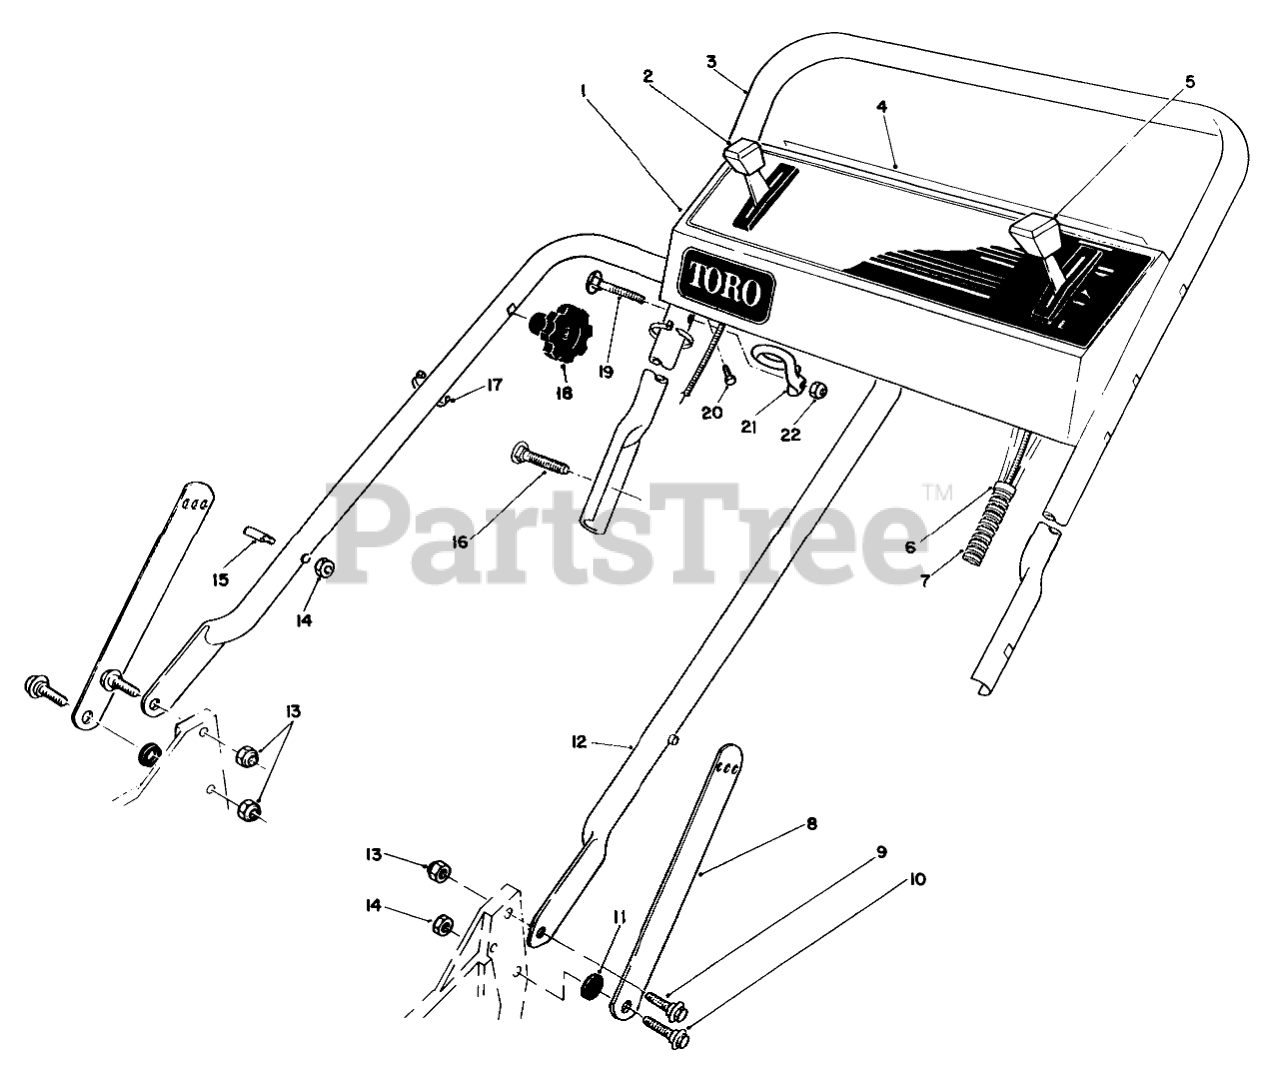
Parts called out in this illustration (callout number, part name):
1	Panel-Control
2	Control-Ground Speed
3	UPPER HANDLE
4	DECAL-PANEL, DANGER
5	THROTTLE CONTROL
6	FITTING-RING
7	CONTROL CABLE COVER
8	Handle Latch
9	SCREW-SHOULDER
10	SCREW-SHOULDER
11	SPACER
12	LOWER HANDLE ASM
13	NUT-LOCK, NI
14	NUT-LOCK, NI
15	HANDLE PIN
16	5/16-18 X 2 HNDLE SCREW
17	TIE-CABLE
19	HANDLE SCREW
20	SCREW-HWHTF
21	Guide
22	NUT-LOCK, NI
